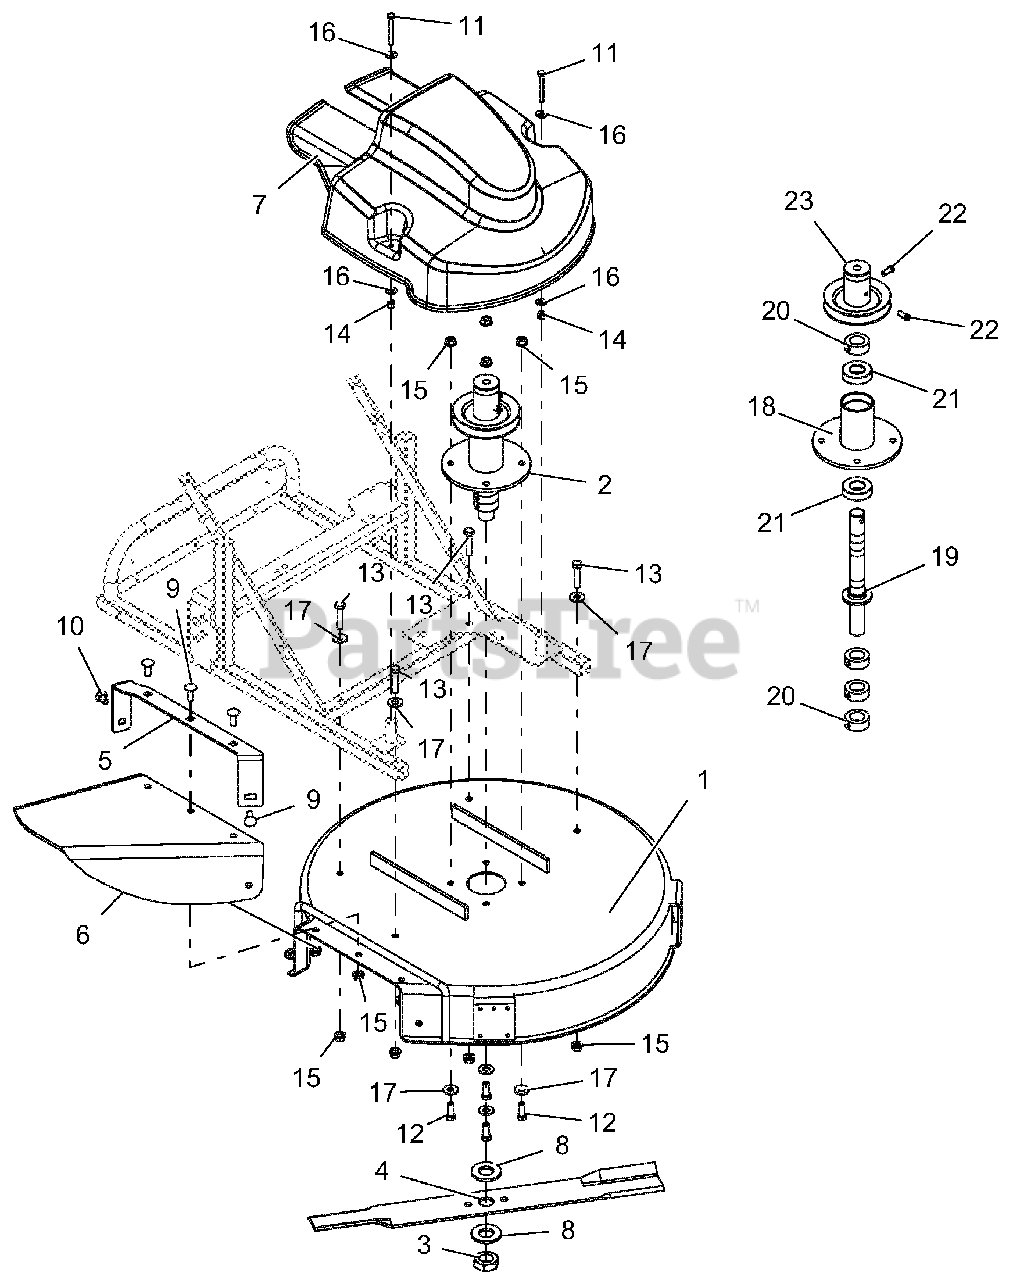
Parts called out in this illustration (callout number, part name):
1	DECAL, ARIENS 24" DECK W/
2	KIT, DECK SPINDLE ASSY, HWM
3	JAM NUT 1-14 NF 15614
4	BLADE KC-24"
5	MOUNT, RUBBER DISCH. CHUTE-HWM
6	CHUTE, RUBBER DISCHARGE
7	COVER, PLASTIC BELT-HIGH WHEEL
8	1"USS WASHER HARD NO PLA 33852
9	@BLT-RDHDSQNK .38-16X1.00 G5YZ
10	@BLT-RDHDSQNK .38-16X.75 G5YZ
11	@BLT-HEX .25-20X2.25 GR5 YWZC
12	@BLT-HEX .38-16X1.00 GR5 YWZC
13	@BLT-HEX .38-16X1.75 GR5 YWZC
14	@NUT-LK-NYL .250-20 YWZC
15	@NUT-LK-TOP-FLG .38-16 YWZC
16	@WSHR-FL-STL.312X.734X.065 YWZ
17	@WSHR-FL-STL.438X1.00X.083 YWZ
18	WMT-SPINDLE, HW MOWER 17304K
19	WMT-SPINDLE SHAFT, HWM 18876K
20	LOCKING COLLAR 1IN 50022213
21	BEARING 1.00 ID X 2 50019553
22	SCR-SET .31-18X.75 SQHCUP HT
23	DOUBLE BLADE SHAFT PULLEY
